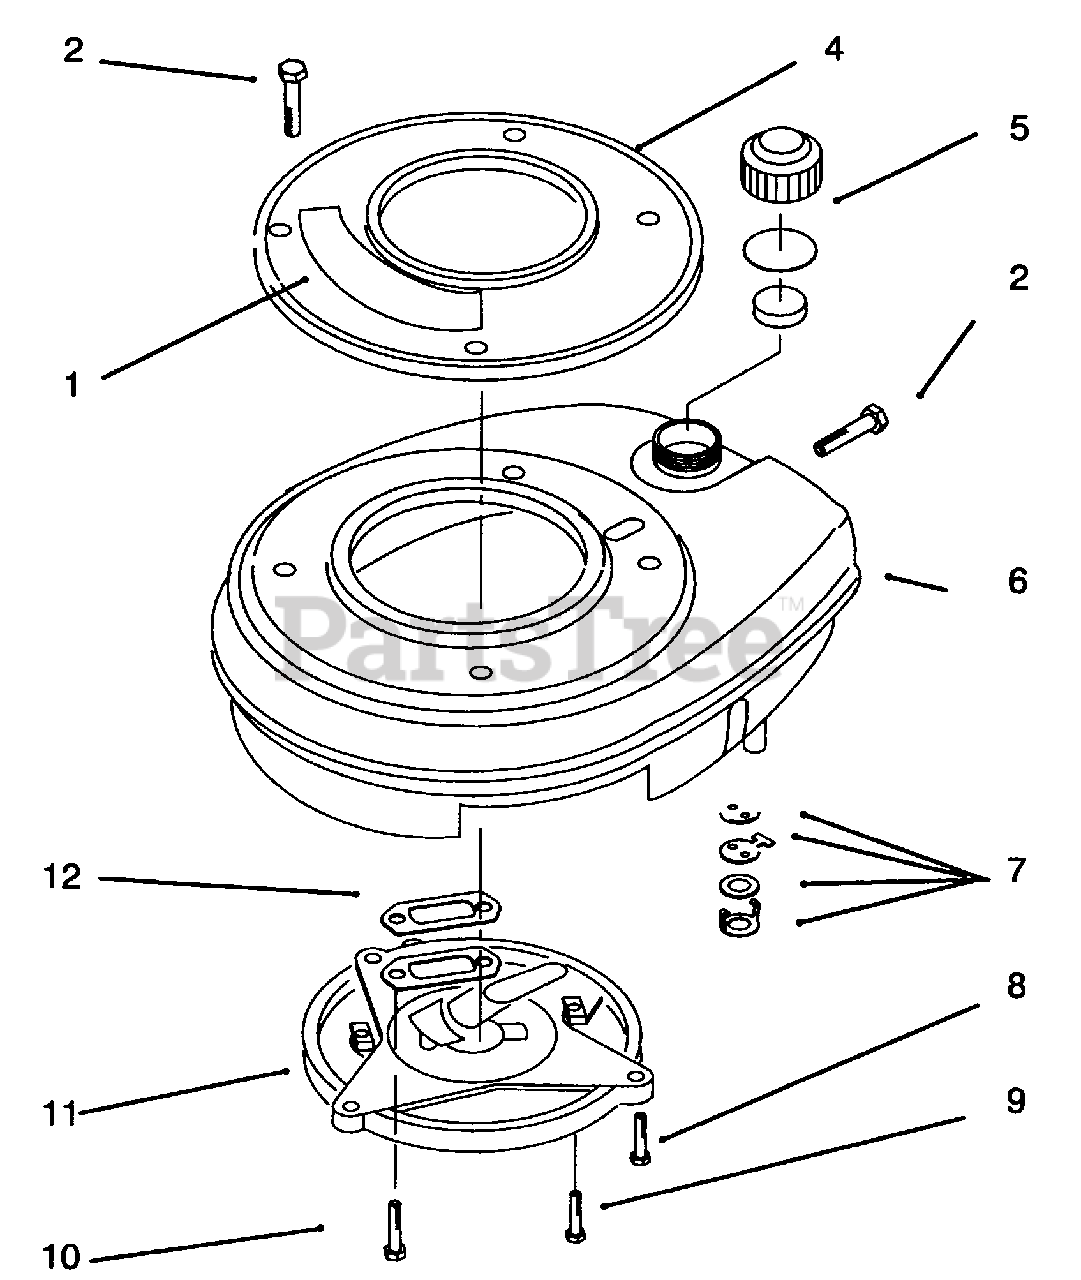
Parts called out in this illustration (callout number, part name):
1	Applique
2	Screw
4	Starter Base
5	Fuel Cap
6	Shroud-Engine
7	Fuel Shut-Off Assembly
8	Screw-Muffler Plt. to Hsg.
9	Screw-Muffler Plt. to Block
11	Plate-Muffler
12	Gasket-Exhaust
